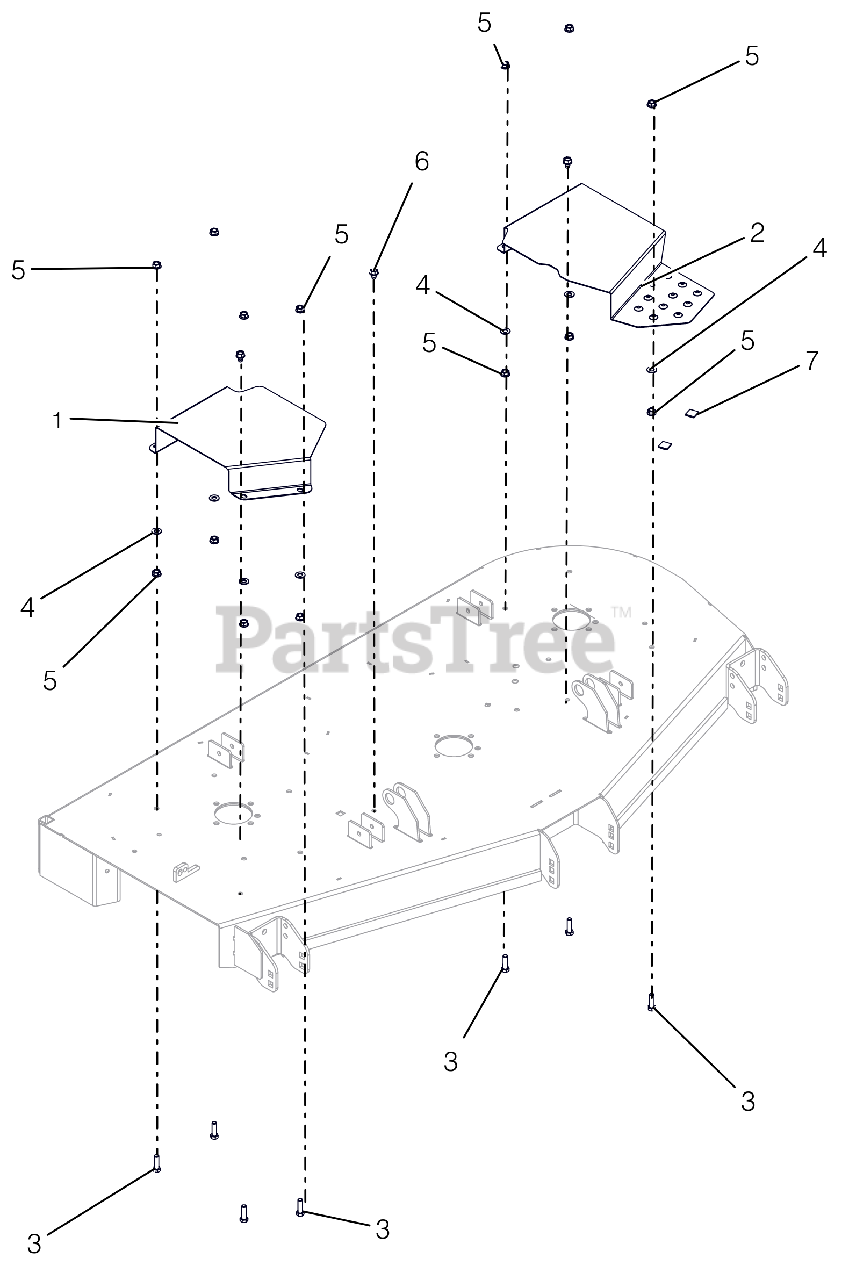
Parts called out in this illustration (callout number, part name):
1	COVER, BELT 52" & 60" RIGHT
2	COVER, BELT 60" LEFT
3	@BLT-HEX .38-16X1.25 GR5 YWZC
4	@WSHR-FL-STL.406X.812X.065 YWZ
5	@NUT-SPNLK-FLG .375-16 YWZC
6	@SCR-TAP .38-16X.50 HWH TR YWZ
